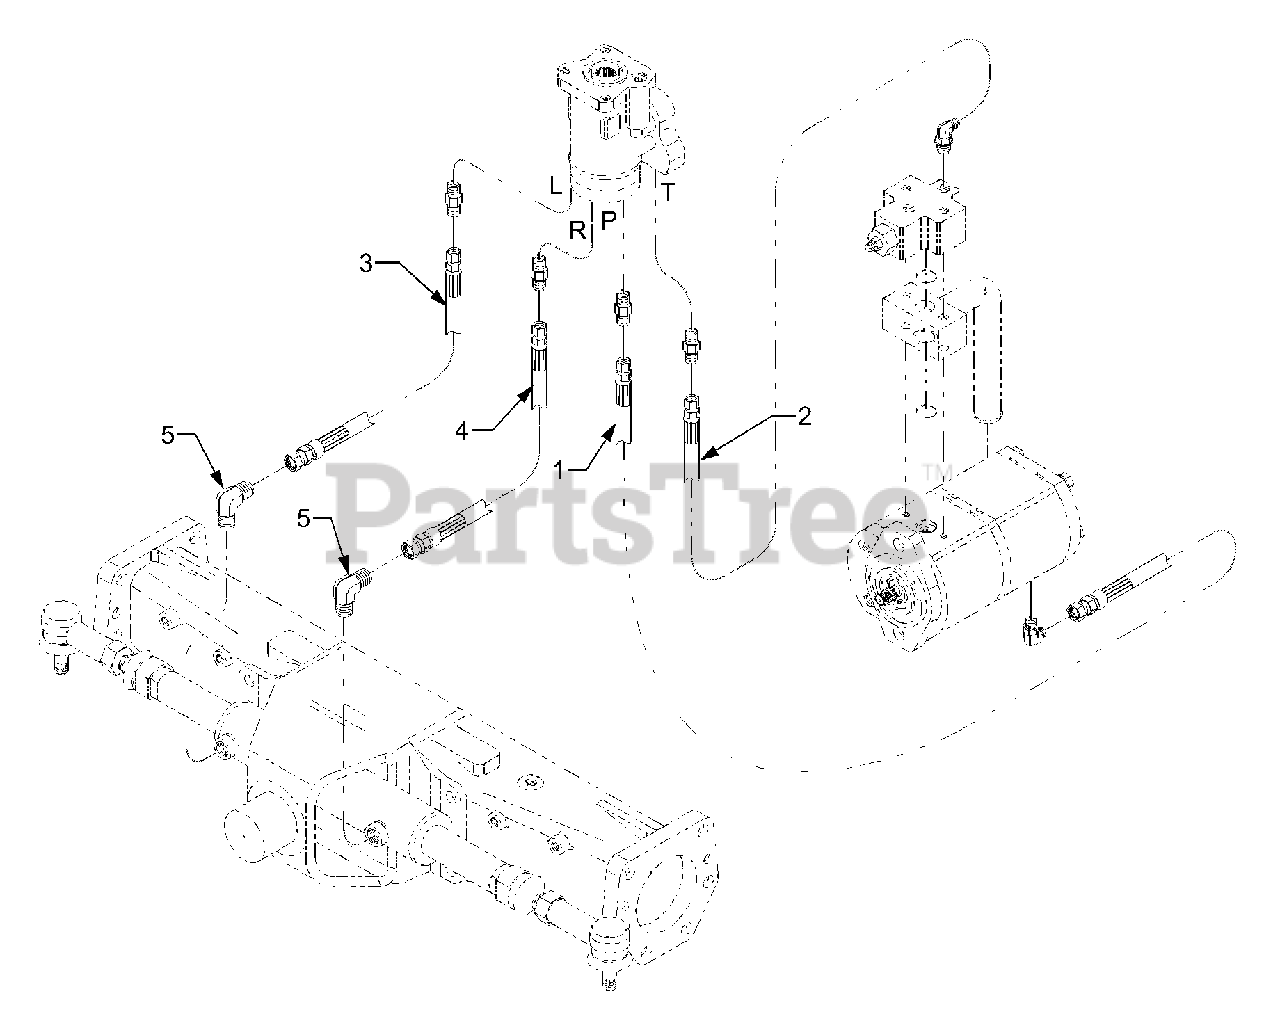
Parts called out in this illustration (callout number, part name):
1	Hose P, Steering
2	Hose T, Steering
3	Hose L, Steering
4	Hose R, Steering
5	Adapter, Cylinder
